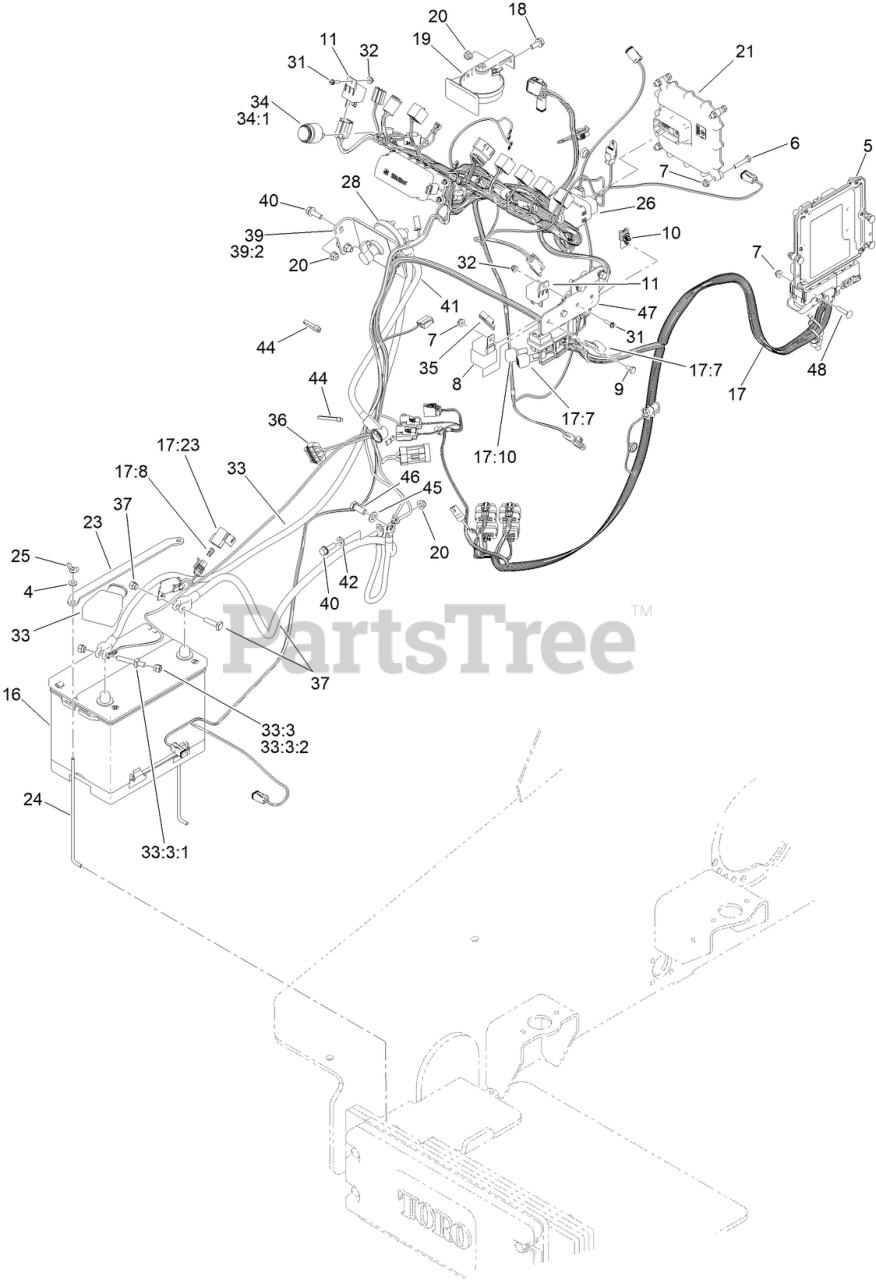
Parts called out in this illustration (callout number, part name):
4	WASHER-FLAT
5	CONTROLLER-ENGINE
6	SCREW-HH
7	NUT-HF
8	RELAY-MINI
9	SCREW-HH
10	CLIP-CONNECTOR
11	RELAY
17	HARNESS-WIRE, ENGINE T4
17:8	FUSE-MINI BLADE, 2 AMP
17:10	RESISTOR-75 OHM
17:23	COVER-FUSE, SINGLE
18	SCREW-HHF
19	Horn And Bracket Assembly (Inc. Ref.# 44 45)
20	NUT-HF, NI
21	CONTROLLER
23	STRAP-HOLD DOWN, BATTERY
24	ROD-HOLD DOWN, BATTERY
25	NUT-WING
26	HARNESS-WIRE, TX1300
28	SWITCH-DISCONNECT, MASTER
31	SCREW-HWH
32	NUT-HF
33	CABLE-BATTERY, RD ASM
33:3	BOLT ASM
33:3:1	BOLT-CLAMP, BATTERY
33:3:2	NUT-CLAMP, BATTERY
34	AUDIO ALARM ASM
34:1	NUT-PLASTIC, KNURLED
35	HARNESS-WIRE, FUSIBLE LINK
36	HARNESS-WIRE, FUSIBLE LINK
37	CABLE-BATTERY, NEGATIVE
39	BRACKET-SHUTOFF
39:2	DECAL-BATTERY DISCONNECT
40	SCREW-HHF
41	CABLE-BATTERY, RD ASM
42	WASHER-PLAIN
44	TIE-CABLE
45	WASHER-FLAT
46	SCREW-HH
47	BRACKET-RELAYS
48	SCREW-CARR
